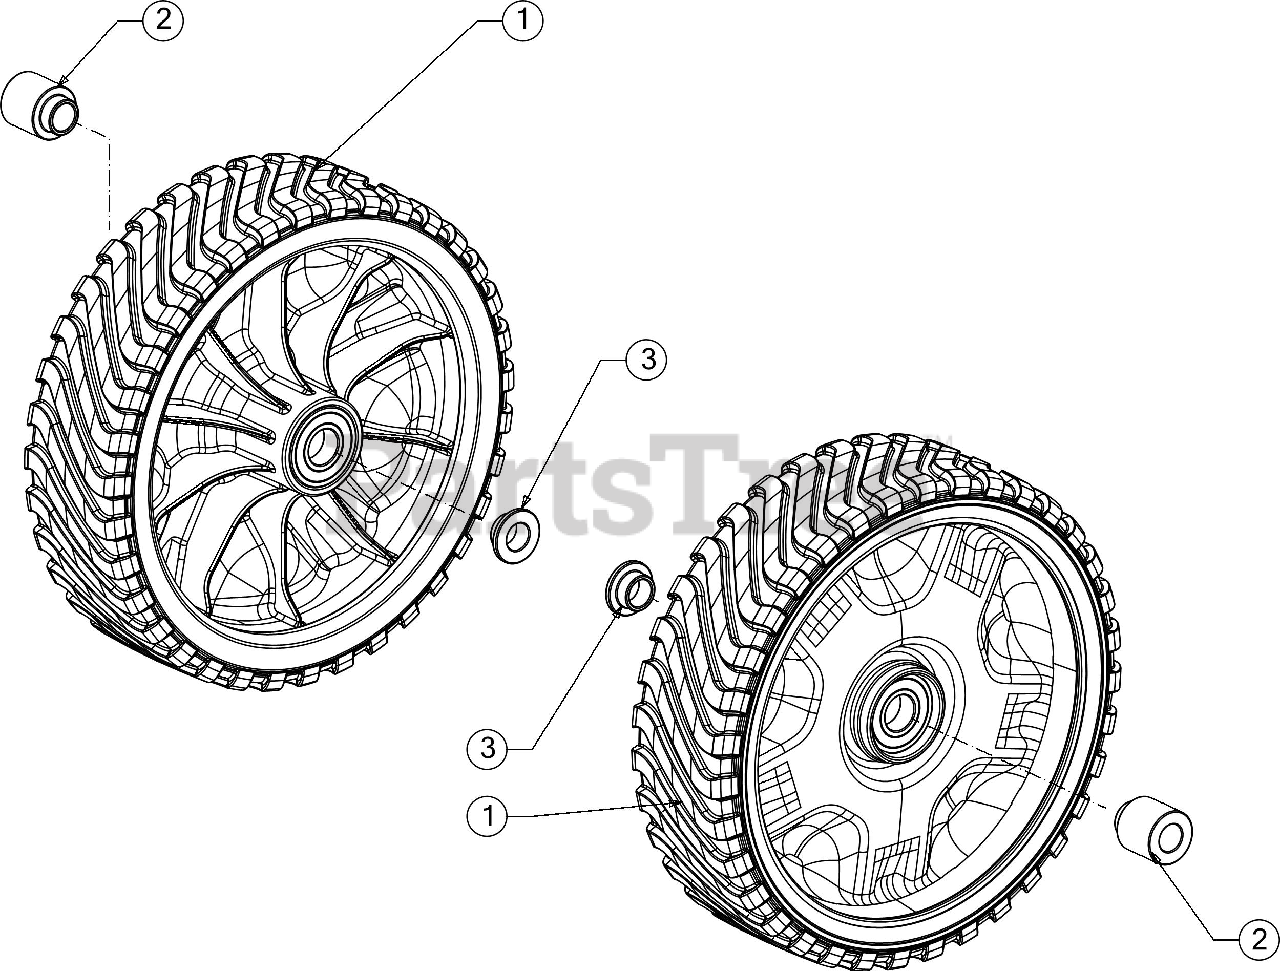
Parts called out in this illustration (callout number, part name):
1	WHEEL ASSEMBLY (7 x 2)
1	BALL BEARING
2	CASTER HUB
3	CASTER HUB
